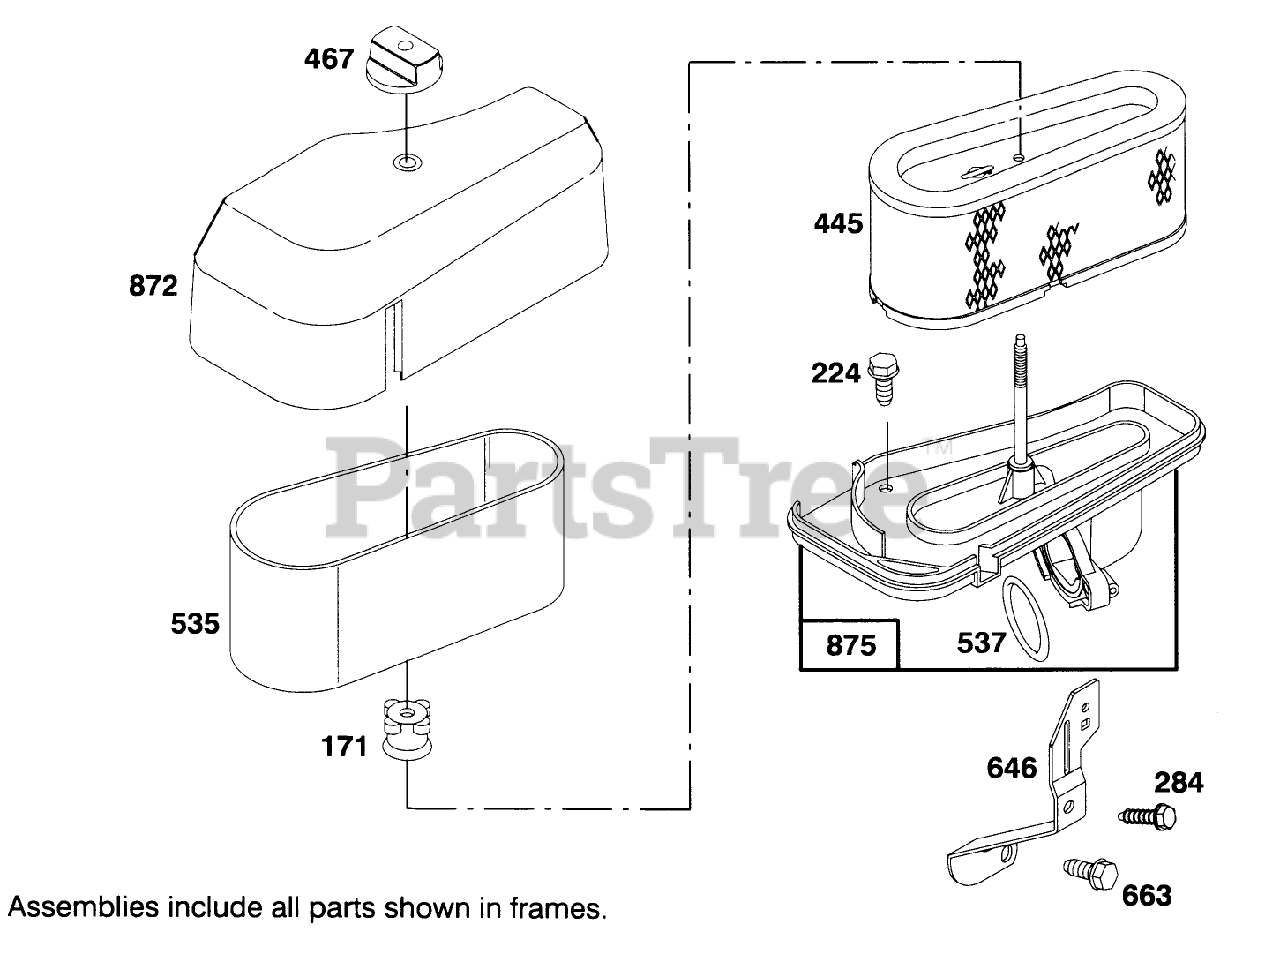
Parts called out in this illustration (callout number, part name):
224	Screw-Sem
284	Screw
445	Filter-Air
535	Filter-Air
537	O-Ring
646	Brace-Air Cleaner
663	Screw
872	Cover-Air Cleaner
875	Base-Air Cleaner
